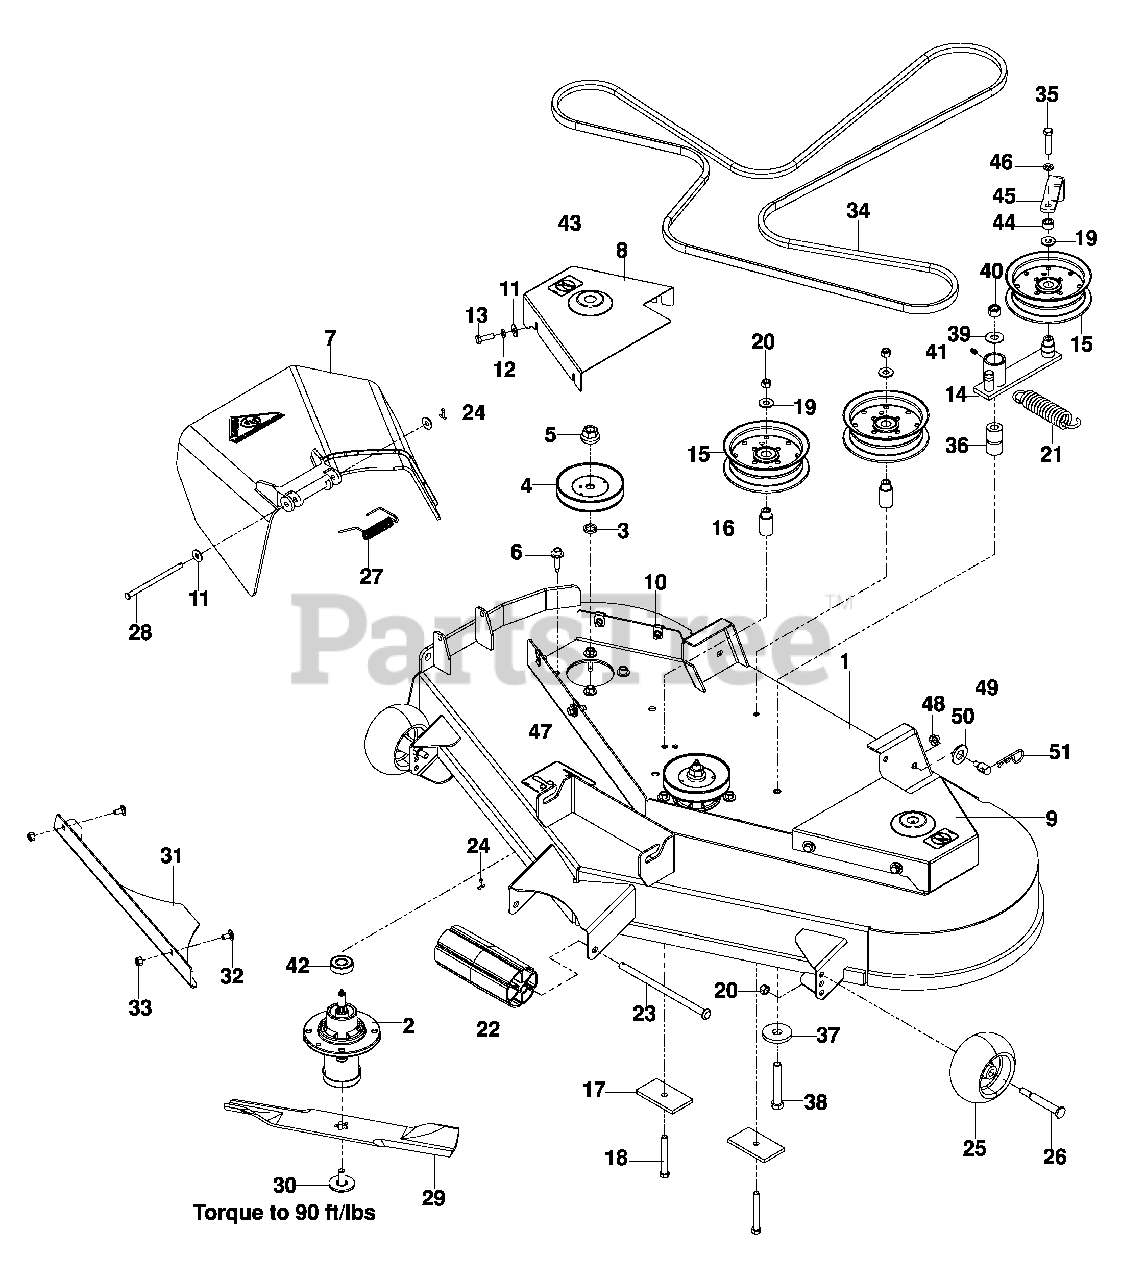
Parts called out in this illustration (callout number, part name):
1	DECK, w/DECALS
2	HOUSING ASSY
3	WASHER, SPACER
4	PULLEY, MANDREL 965880401
5	PULLEY, MANDREL 966495801
6	NUT 9/16 TOP CNTRLK
7	SCREW 5/16 -18 x WSH HD
8	CHUTE, DISCHARGE
9	BELT SHIELD, RT
10	BELT SHIELD, LT
11	RETAINER, U TYPE
12	WASHER 5/16 STD FLAT
13	WASHER 5/16 SLW
14	HCS 5/16-18 x 1
15	ARM, IDLER
16	PULLEY, IDLER
17	BUSHING, IDLER
18	PAD, PAINTED
19	HCS 3/8-16 x 3
20	WASHER 3/8 FLAT STD
21	NUT 3/8-16 HEX NYLOC
23	ROLLER, NOSE
24	ROD, ROLLER, NOSE
25	PIN, COTTER 1/8 x ¾
26	WHEEL, GAUGE
27	BOLT ½-16 x 25/8 SHOULDER
28	SPRING, TORSION
29	PIN, CLEVIS 5/16
31	BOLT 7/16 BLADE
32	PLATE, CONFINEMENT
33	RHSNB 5/16-18 x 5/8
34	NUT 5/16-18 HEX NYLOC
35	BELT, DECK 965880401
36	BELT, DECK 966495801
37	HCS 3/8-16 x 1¾
38	BUSHING, PIVOT
39	WASHER, SUPPORT
40	HCS ½-13 x 3¼
41	WASHER ½ STD FLAT
42	NUT ½ HEX NYLOC
43	ZERK
44	BEARING, BALL
45	DECAL, NO STEP
47	GUIDE, BELT
48	WASHER 3/8 SPLT LOCK
49	DECAL, BELT ROUTING
50	NUT 5/16-18 FLANGE NYLOC
52	WASHER 5/8, SAE
53	HAIRPIN #4
